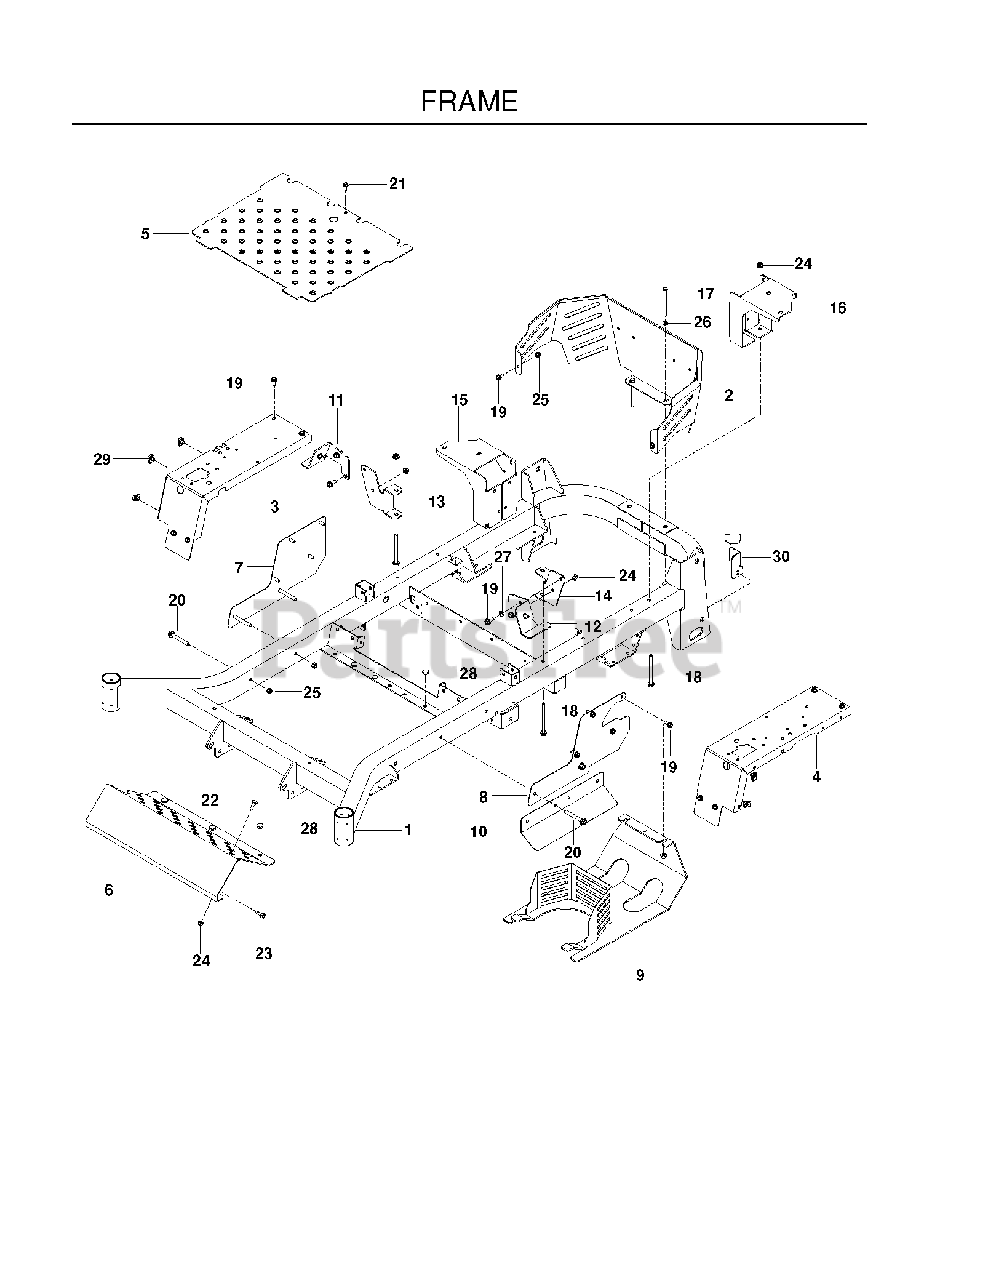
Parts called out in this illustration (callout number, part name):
3	PANEL, FILLER RT, BLUE
4	PANEL, FILLER LT, BLUE
5	FLOOR PAN W/DECALS
6	PLATE, FOOT REST - RAM DK BLUE
7	SIDE, RT, BL
8	SIDE, LT, BL
11	MOUNT, TANK, RT-BLK
12	MOUNT, TANK, LT-BLK
17	HCS 5/16C X 4
18	HHFS 5/16-18 X 3 3/4
19	HHFS 5/16-18 X 3/4
20	HHFS 3/8-16 X 2 3/4
21	HHFS 5/16-18 X 3/4
22	RHSNB 5/16C X 1
23	BLT 5/16-18 X 1 THRD FORM ZD
24	5/16-18 NYLOC FLANGE NUT
25	NUT HEX 3/8-16 NYLON, THIN
26	FLAT WASHER 5/16 SAE
27	WASH 5/16 DISC SPRING ZD
28	GROMMET, BUMPER
29	U-CLIP 5/16-18 NUT RETAINER
